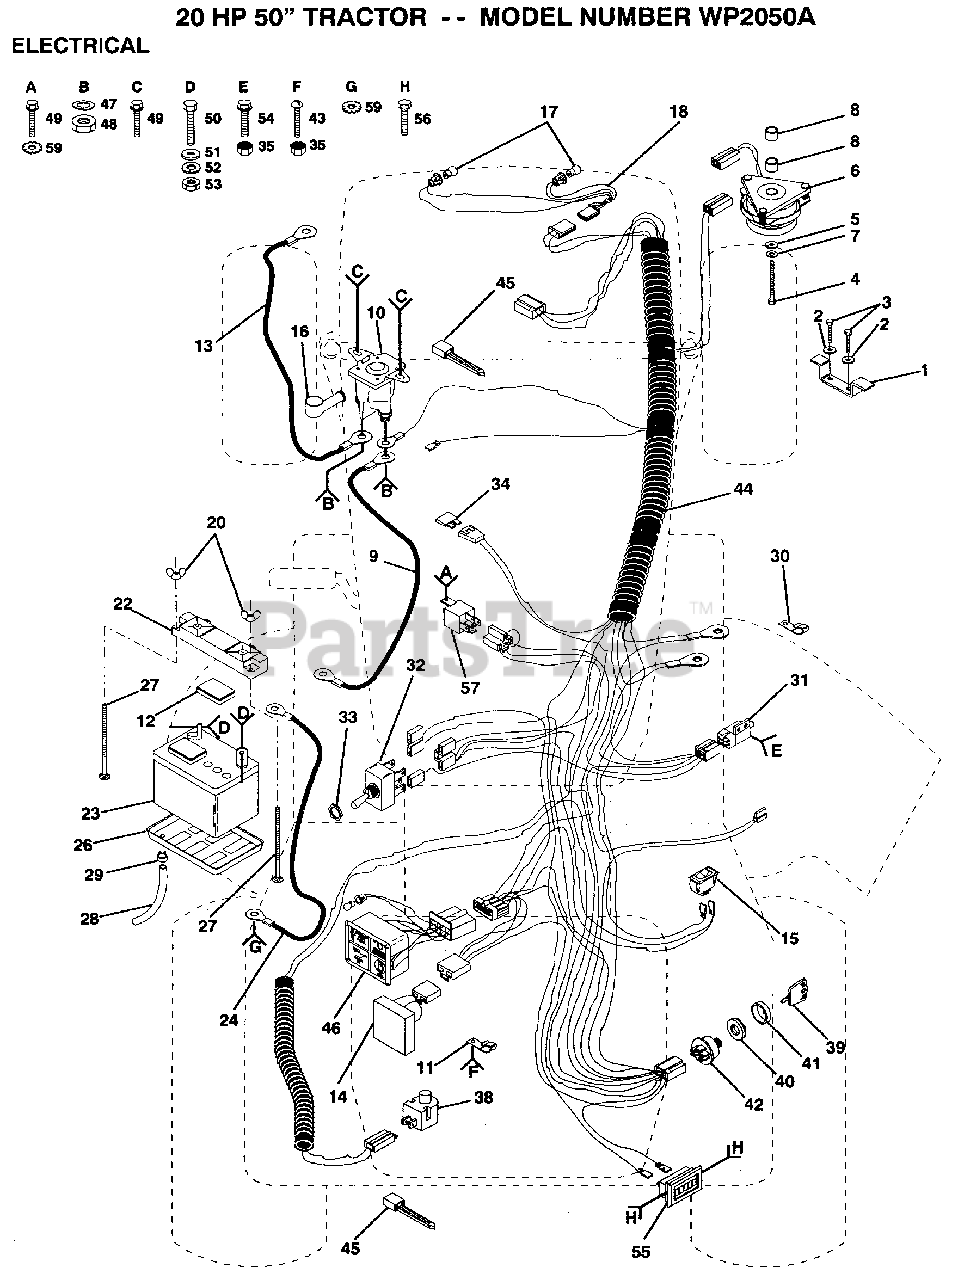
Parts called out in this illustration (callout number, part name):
2	LOCKWASHER
3	BOLT
5	WASHER
7	LOCKWASHER
8	SPACER-CLUTCH
9	CABLE-BATTERY T
12	"CAP,BATTERY "
13	"CABLE,STARTER T"
14	SENSOR LOW VOLT T
15	SWITCH LT
24	CABLE T
26	"TRAY T, BATTERY"
27	BOLT
29	HOSE CLAMP T
30	CLIP GTV
31	SWITCH INTERLOCKT
33	HEX NUT T
34	FUSE HYT
35	"NUT,KEPS"
38	SWITCH SEAT
39	KEY
40	NUT IGNITION
44	HARNESS
45	WIRE TIE
46	INDICATORLIGHTT
48	NUT
49	SCREW ST
50	BOLT LT
51	WASHER
52	LOCKWASHER
54	SCREW
55	HOUR METER T
56	SCREW
57	RELAY ASSY T
59	LOCKWASHER
